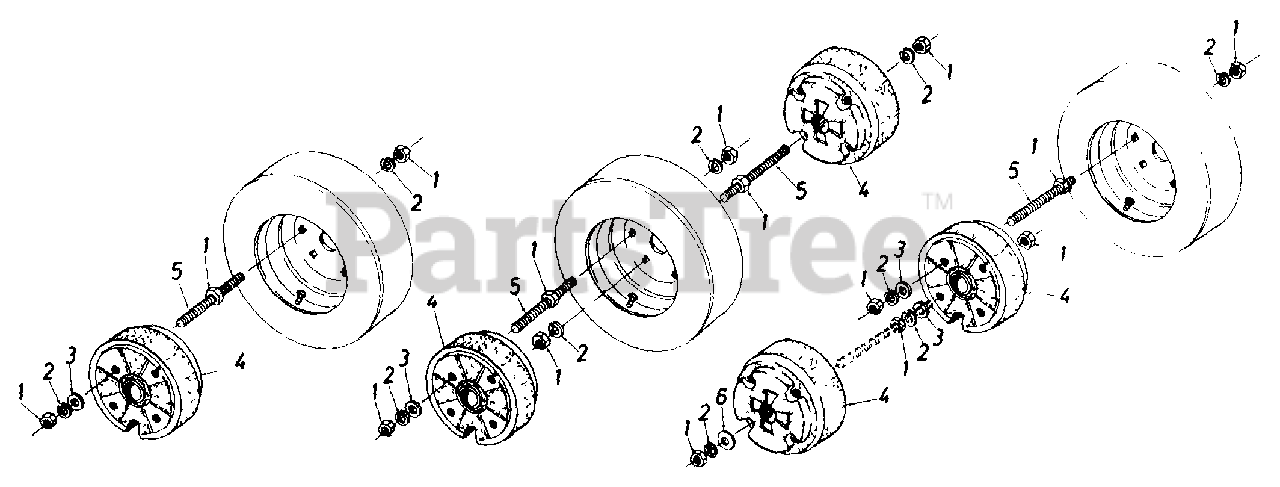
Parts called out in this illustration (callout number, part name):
1	Hex Nut 1/2-13 Thd.
2	Lock Wash. 1/2" I.D.
3	Fl-Wash..53" I.D. x .93" O.D.
4	Wheel Weight
5	Rod Threaded 1/2-13 x 9 5" Lg.
6	Fl-Wash..5" 1.0 x 2.0" O.D.
